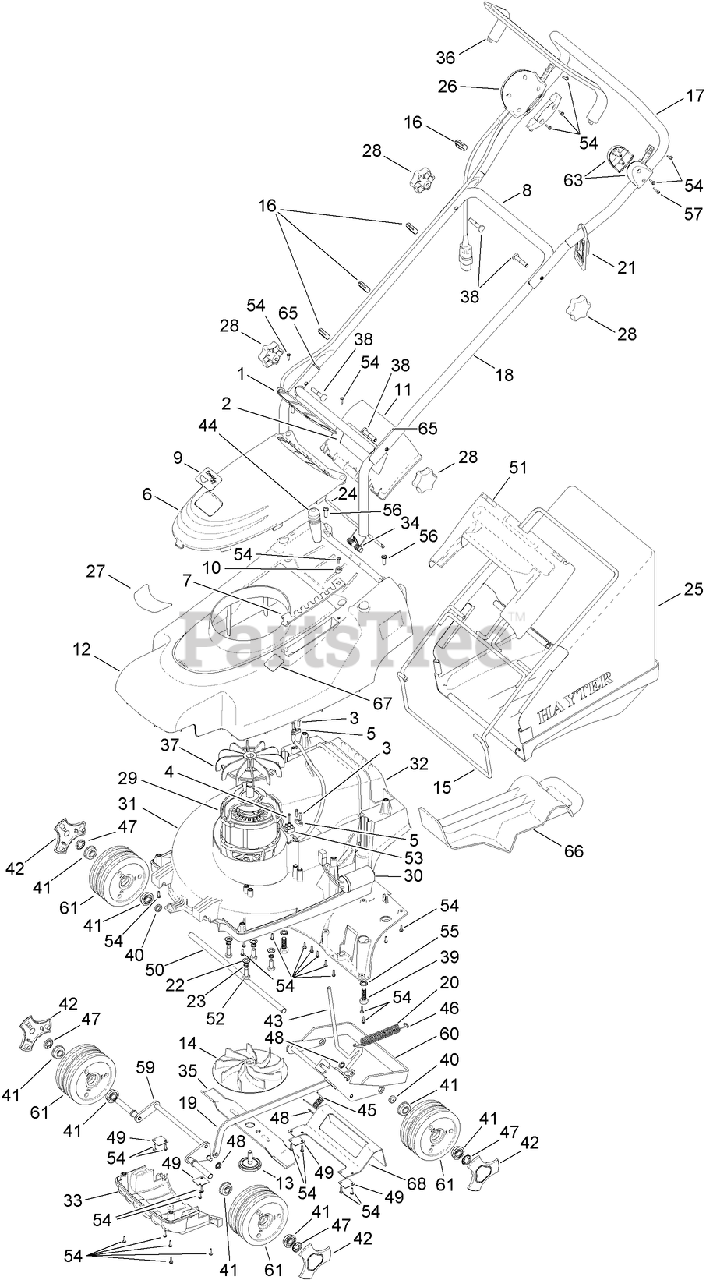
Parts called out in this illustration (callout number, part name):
1	VENT MESH ASM
2	DECAL-SAFETY, ELECTRIC
5	CLAMP-CABLE
6	COVER-MOTOR
7	PLATE-HOC
8	HANDLEBAR-LOWER
9	DECAL-TORO
10	COVER-SCREW, HOC
11	DEFLECTOR-REAR
12	COVER-TOP
13	BOLT-FIXING, CUTTERBAR (NYLON)
14	CARRIER-CUTTERBAR
15	FRAME-GRASSBAG
16	CLIP-CABLE
17	HANDLEBAR-UPPER
18	HANDLEBAR-MIDDLE
19	ROD-CONNECTING
20	SPRING-BALANCE, COUNTER
21	CLEAT-CABLE
22	Sealant-Liquid
23	WASHER-SPRING
24	ROD-DEFLECTOR
25	GRASSBAG
26	SWITCH AND LEAD ASM
28	KNOB-HANDLEBAR
29	MOTOR
30	CAPACITOR
31	UNDERDECK
32	THROWPLATE
34	SPRING-DEFLECTOR
35	CUTTERBAR
36	ARM-BAIL
37	FAN-TOP, MOTOR
38	BOLT-HANDLEBAR
39	SCREW-HH
40	SPACER-WHEEL, REAR
41	BEARING-WHEEL
42	CAP-HUB
43	LEVER-HOC
44	KNOB-HOC
45	SPRING-HOC
46	PIN-SPRING, HOC
47	WASHER-STARLOCK
48	WASHER-STARLOCK, 8mm
49	PLATE-PIVOT, AXLE
50	ROD-AXLE, REAR
51	TOP-GRASSBAG
52	BOLT-MOTOR
53	BLOCK-TERMINAL
55	WASHER
56	SCREW-PPH, THREAD FORMING
57	SCREW-PPH
59	FRONT AXLE ASM
60	REAR AXLE ASM
61	WHEEL ASM
63	MOUNT BAIL ARM ASM
65	PLUG-TUBE
66	PLUG-MULCHING
67	DECAL-HOC
68	GUARD-PLATE, AXLE
